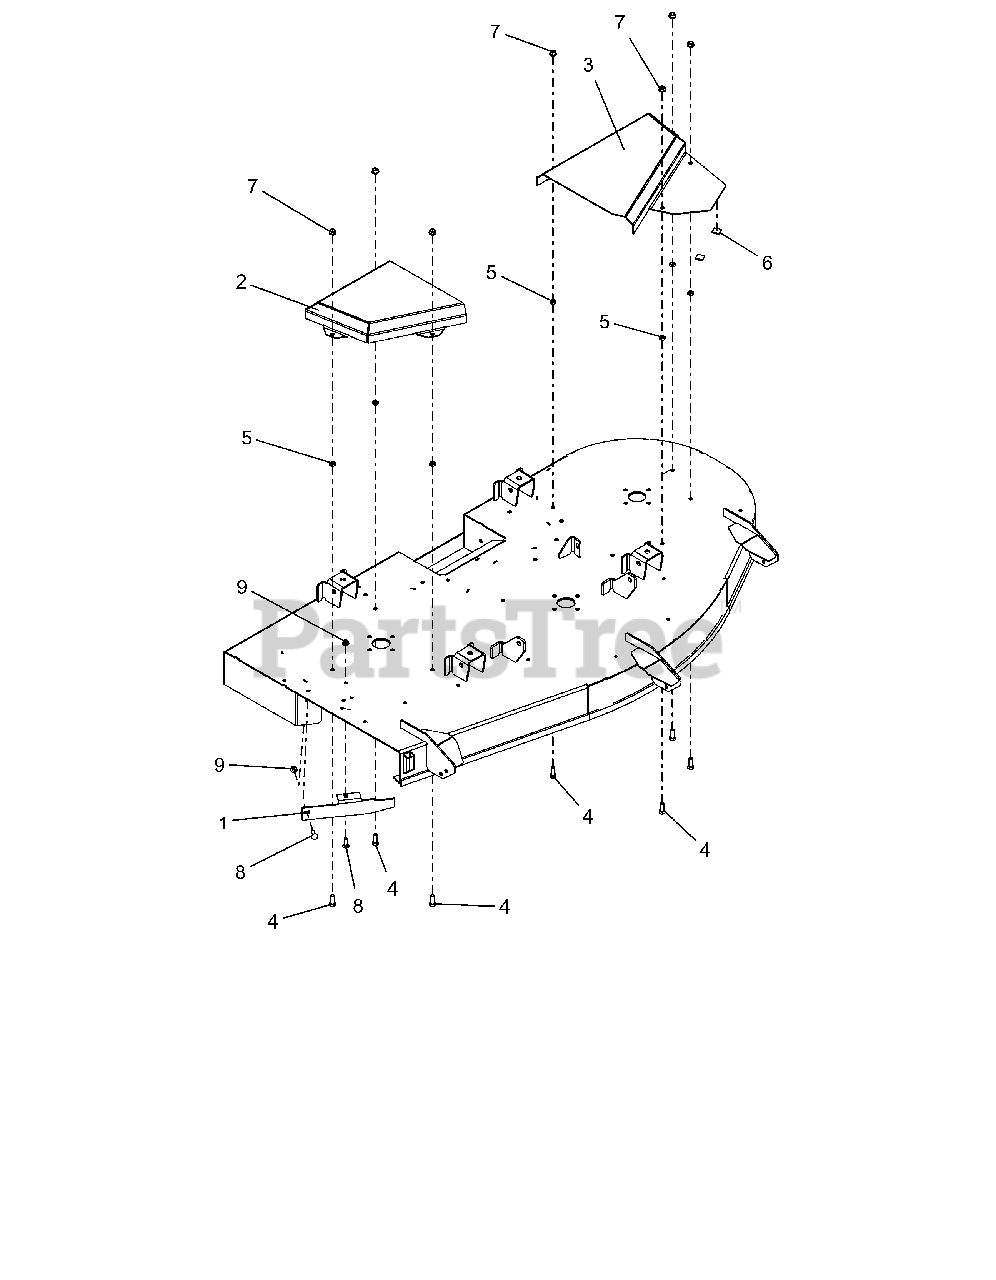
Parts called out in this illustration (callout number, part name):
1	BAFFLE, DISCHARGE 60"
2	COVER, BELT RH 60"
3	COVER, LH BELT 60
4	BLT,HEX .38-16X1.00 G5 ZCC
5	NUT-HEX-JAM .375-16 YWZC
7	NUT-LK-TOP-FLG .38-16 ZC120
8	BLT,RHSN .31-18X1.00 G5 ZCC
9	NUT,NYL-FLG .31-18 GF ZCC
